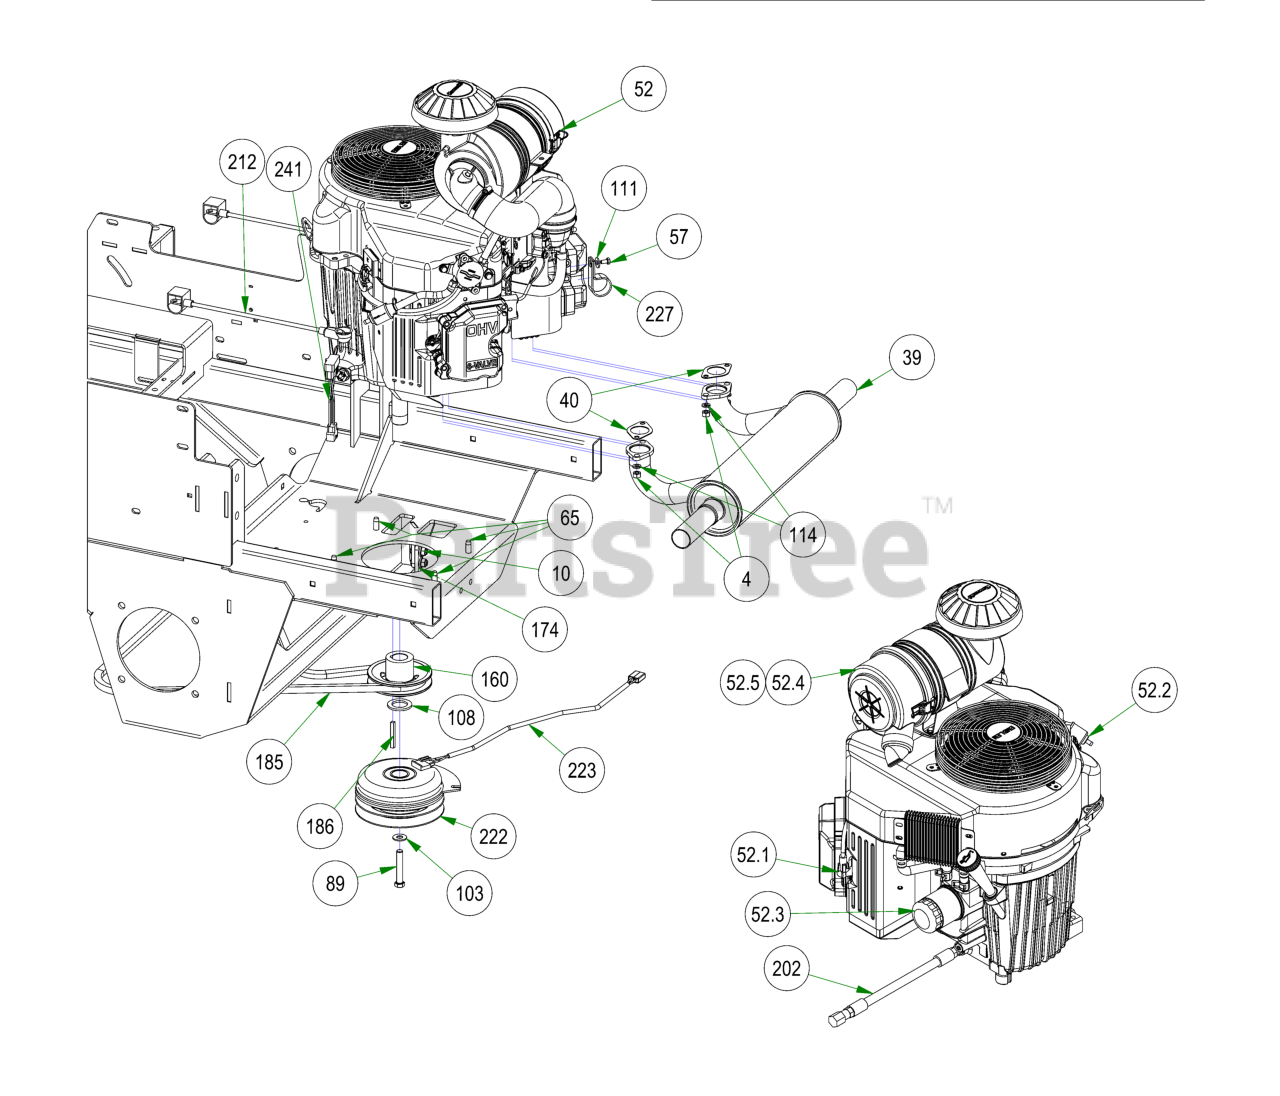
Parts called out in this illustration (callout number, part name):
4	M8-1.25 DIN 934 HEX NUT (CL.8) ZINC
10	3/8-16 NYLON INSERT FLANGE LOCKNUT (GR.F) ZINC
39	2019 Rebel/Rogue Kawasaki 1000 Muffler
40	Exhaust Gasket
52	Kawasaki FX1000 Engine
52.1	Spark Plug - Kawasaki
52.2	Universal Inline Fuel Filter
52.3	Oil Filter
52.4	Canister Air Filter- Outer
52.5	Canister Air Filter- Inner
52.6	Exhaust Gasket
57	M6-1.0 X 12MM DIN 933 HEX TAP BOLT (CL 8.8) ZINC
65	3/8-16 X 1-1/8HEX WASHER UNSLOT SERRATED
87	3/8-16 X 1 CARRIAGE BOLT (GR.5) ZINC
89	7/16-20 X 2-1/2 HEX Bolt GR 8 W/ Patch
103	3/8 FLAT WASHER USS (1" OD) ZINC
108	1.140 ID X 1.750 OD X .132 THICK FLAT WASHER PLAIN
111	1/4 USS FLAT WASHER (3/4 OD) ZINC
114	5/16 SPLIT LOCKWASHER ZINC
160	4 3/4 Motor Pulley
174	Rebel Clutch Tab
185	2019 Rebel Pump Belt
186	1/4 X 2 SQ MACHINERY KEY 1018 STL PLAIN
202	Kawasaki Oil Drain
212	14" Red Battery Cable-Base Outlaw
222	Clutch Assembly
223	Clutch Pigtail
224	2023 Rebel Frame - Painted
227	Diesel Hydraulic Hose Clamp
238	Starter Cable
241	2019 Harness Adaptor-Gen2 FX-ALL
